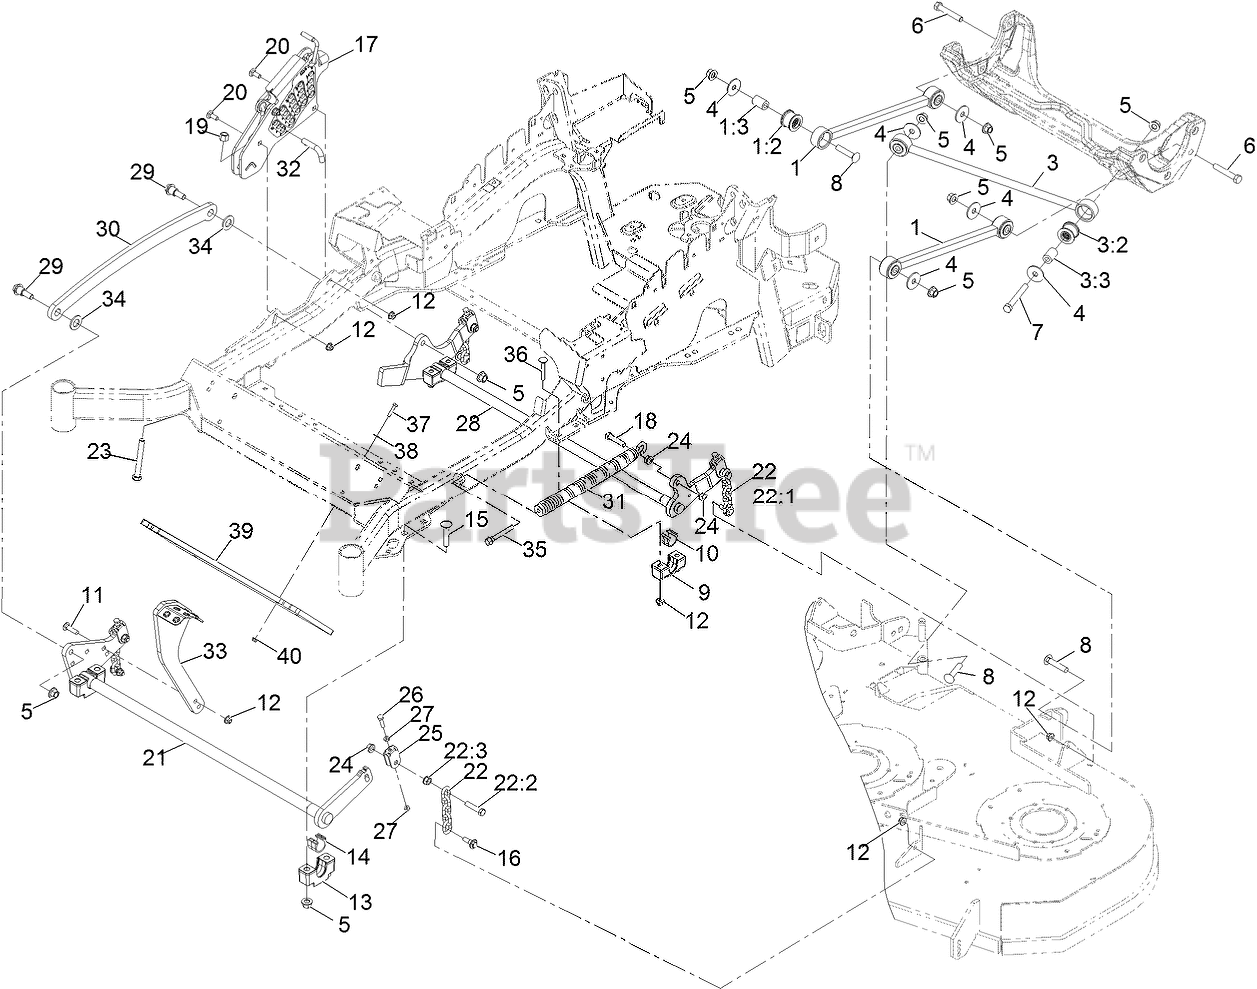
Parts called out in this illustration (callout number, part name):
1	LONG STRUT ASM
1:2	BUSHING-SUSPENSION, RUBBER
3	PANHARD ROD ASM
3:2	BUSHING-SUSPENSION, RUBBER
4	WASHER-THRUST
5	Nut-Lock 1/2-13
6	SCREW-HH
7	SCREW-HH
8	SCREW-CARR
9	SUPPORT-CROSS SHAFT, BEARING REAR
10	BEARING-CROSS SHAFT, REAR
11	SCREW-CARR
12	NUT-HF, NI
13	SUPPORT-CROSS SHAFT, BEARING
14	BEARING-CROSS SHAFT, FRON
15	Bolt-Carriage 1/2-13 X 2 1/2 Spl Neck
16	SCREW-SHOULDER, HHF
17	HOC ASM
18	SCREW-HH
19	NUT-LOCK, NI
20	BOLT-CARR
21	DECKLIFT-FRONT
22	DECK LIFT CHAIN ASM
22:1	CHAIN-LIFT, DECK
22:2	SCREW-HH
23	BOLT-TAP
25	YOKE-ADJUST, DECK
26	SCREW-HH
27	NUT-JAM
28	LIFT-DECK, REAR
29	SCREW-SHOULDER, HHF 1/2-13 X 1.12
30	LINK-LIFT, DECK
31	SPRING-EXTENSION
32	PIN-HOC
33	LEVER-FOOT
34	WASHER-FLAT
35	BOLT-SHOULDER
36	Bolt-Carriage 3/8-16 X 2 1/4
37	SCREW-HH
38	WASHER-FLAT
39	WEIGHT-TOE BOARD
